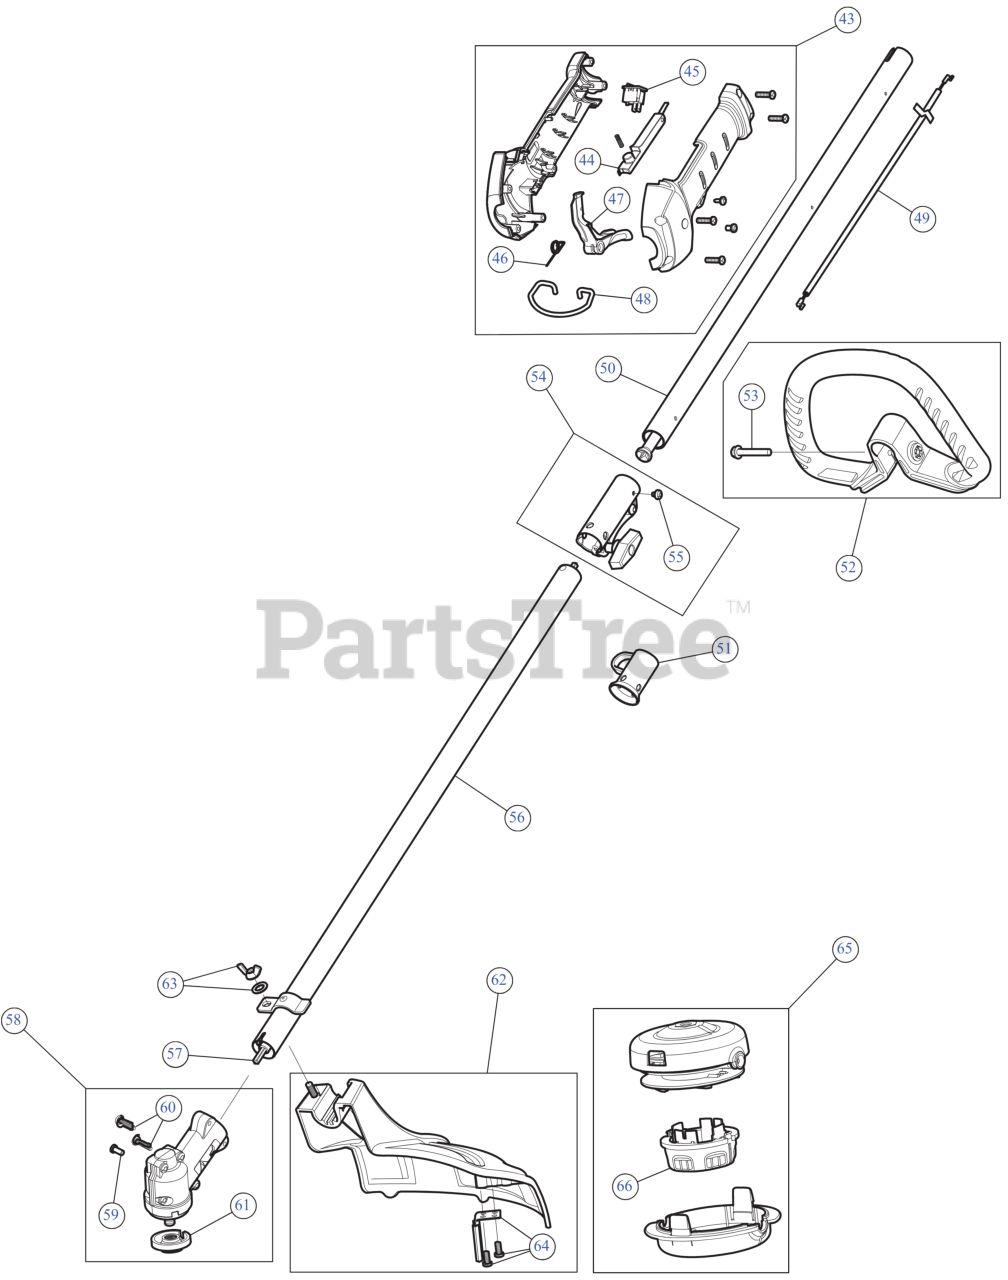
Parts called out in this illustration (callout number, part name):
43	THROTTLE GRIP ASM
44	THROTTLE LVR LKOUT
45	SW, MOMENTARY ON/O
46	SPRING TRIG
47	THROTTLE TRIGGER
48	SHOULDER STRAP CLIP
49	THROTTLE CABLE
50	UPPER BOOM ASSEMBLY
51	HANGER
52	HANDLE ASSEMBLY
53	BOLT 1/4-20X1 1/2
54	SPLIT BOOM COUPLER KIT
55	SCREW, 10-32X.250 TA
56	LOWER BOOM ASSEMBLY
57	LOWER DRIVE SHAFT
58	GEARBOX LCBC
59	SCREW, 8-32 x .312 P
60	SCREW #
61	CUTTING HEAD SPACER
62	GUARD ASSEMBLY
63	BLADE GUARD MOUNTING HARDWARE
64	BLADE ASSEMBLY W/HDW
65	CUTTING HEAD
66	BUMP KNOB
